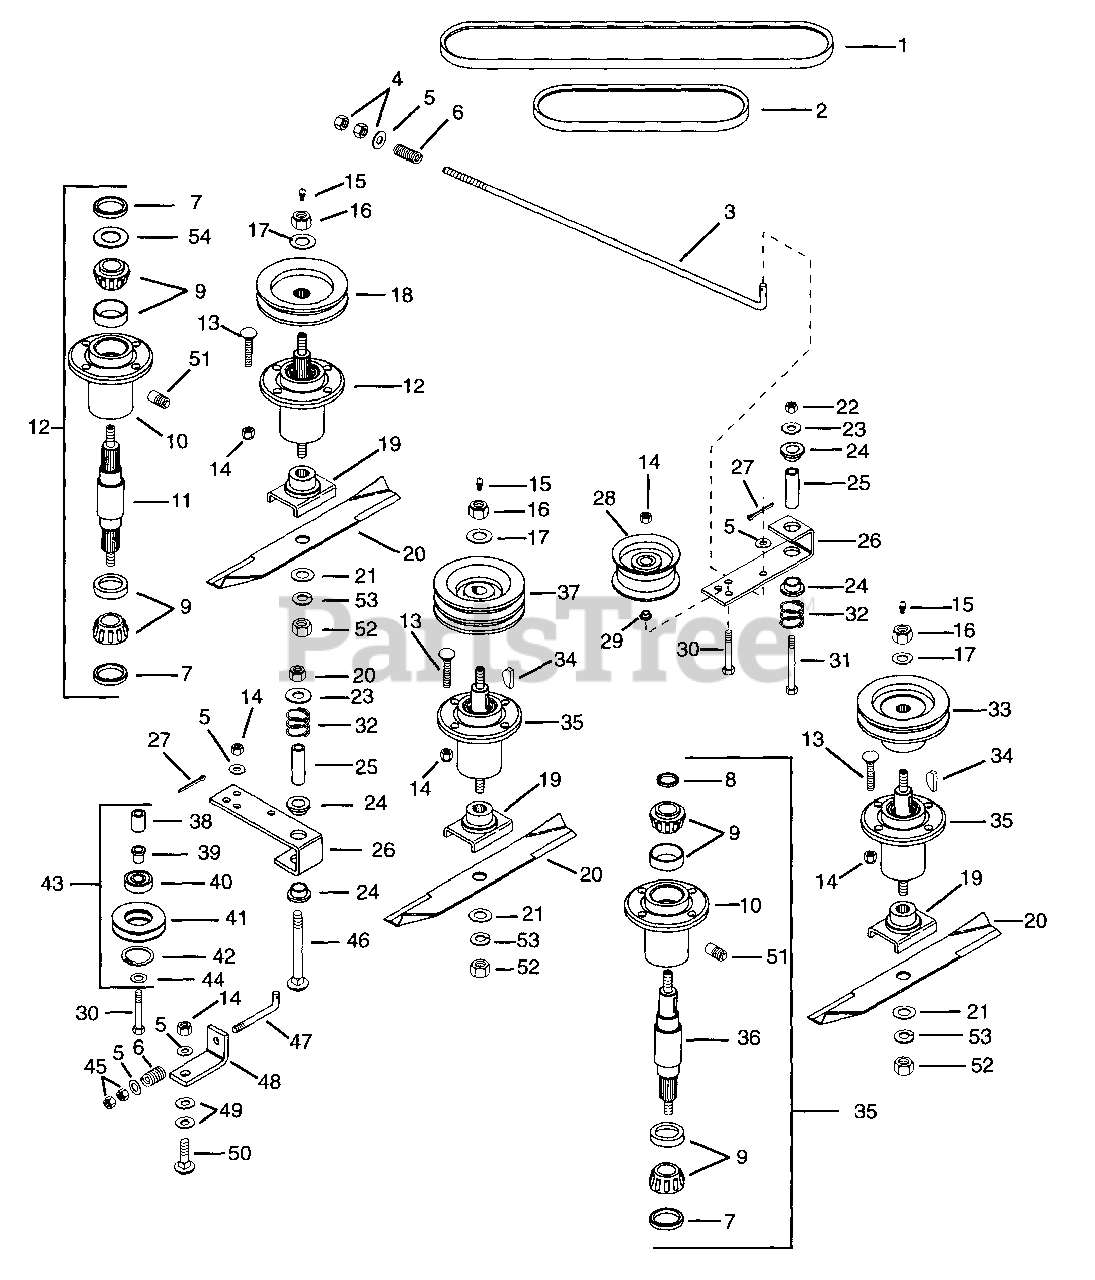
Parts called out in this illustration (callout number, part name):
1	V-Belt A-Section 45.10 x .495
2	V-Belt A-Section 24.90 x .500/.031
3	Rod, Idler
4	Nut-Hex .375-24 Grade 2
5	Washer-Flat-Steel .406 x .812 x .065
6	Spring-Compression .125 x .78 x 1.00
7	Seal 1.987 x 1.375 x .313
8	Seal 1.987 x 1.500 x .313
9	Assembly, Bearing Cup & Cone
10	Bearing Housing
11	Shaft, Spindle
12	Service Kit Spindle Assembly
13	Bolt-Round Head Square Neck .38-16 x 1.375
14	Nut-Locking-Nylon .375-16 Grade 2
15	Fitting-Lube 1/8
16	Nut-Locking-Nylon .625-11 Grade 2
17	Washer-Flat-Steel .687 x 1.312 x .150
19	Weldment Blade Cradle
20	Blade, 60 Inch Mower
21	Washer-Flat-Steel .656 x 1.312 x .095
22	Nut-Locking .50-13
23	Washer-Flat-Steel .531 x 1.250 x .100
24	Bushing-Flange .762 x 1.0 x .580 x 1.48
25	Spacer .560 x .750 x 2.437
26	Arm, Idler Pivot
27	Pin-Cotter .09 x 1.0
28	Idler-Flat 4-.687 x .38
29	Bushing-Flange .406 x .88 x .270 x .140
30	Bolt-Hex .38-16 x 2.25 Grade 5
31	Bolt-Hex .50-13 x 3.50 Grade 5
32	Spring-Compression .085 x .80 x 1.00
34	Key-Woodruff .25 x 1
35	Service Kit Spindle Assembly
36	Shaft, Spindle
38	Bushing, Steel .406 x .625 x .480
39	Bushing-Flange .786 x 1.0 x .79
40	Bearing-Ball 1.85 x .787 x .55
41	Sheave, Idler
42	Ring-Retaining-Internal 2.054 x .062
43	Assembly, Idler Sheave
44	Washer-Flat-Steel .375 x 1.125 x .065
45	Nut-Hex .375-16 Grade 2
46	Bolt-Round Head Square Neck .50-16 x 3.50
47	Rod, Idler
48	Bracket, Belt Tensioner
49	Washer-Flat-Steel .531 x 1.062 x .095
50	Bolt-Round Head Square Neck .38-16 x 1.25
51	Relief Fitting
52	Nut-Hex .525-11 Grade 2
53	Washer-Lock .625 x .156
54	Washer-Flat-Steel .203 x .469 x .049
